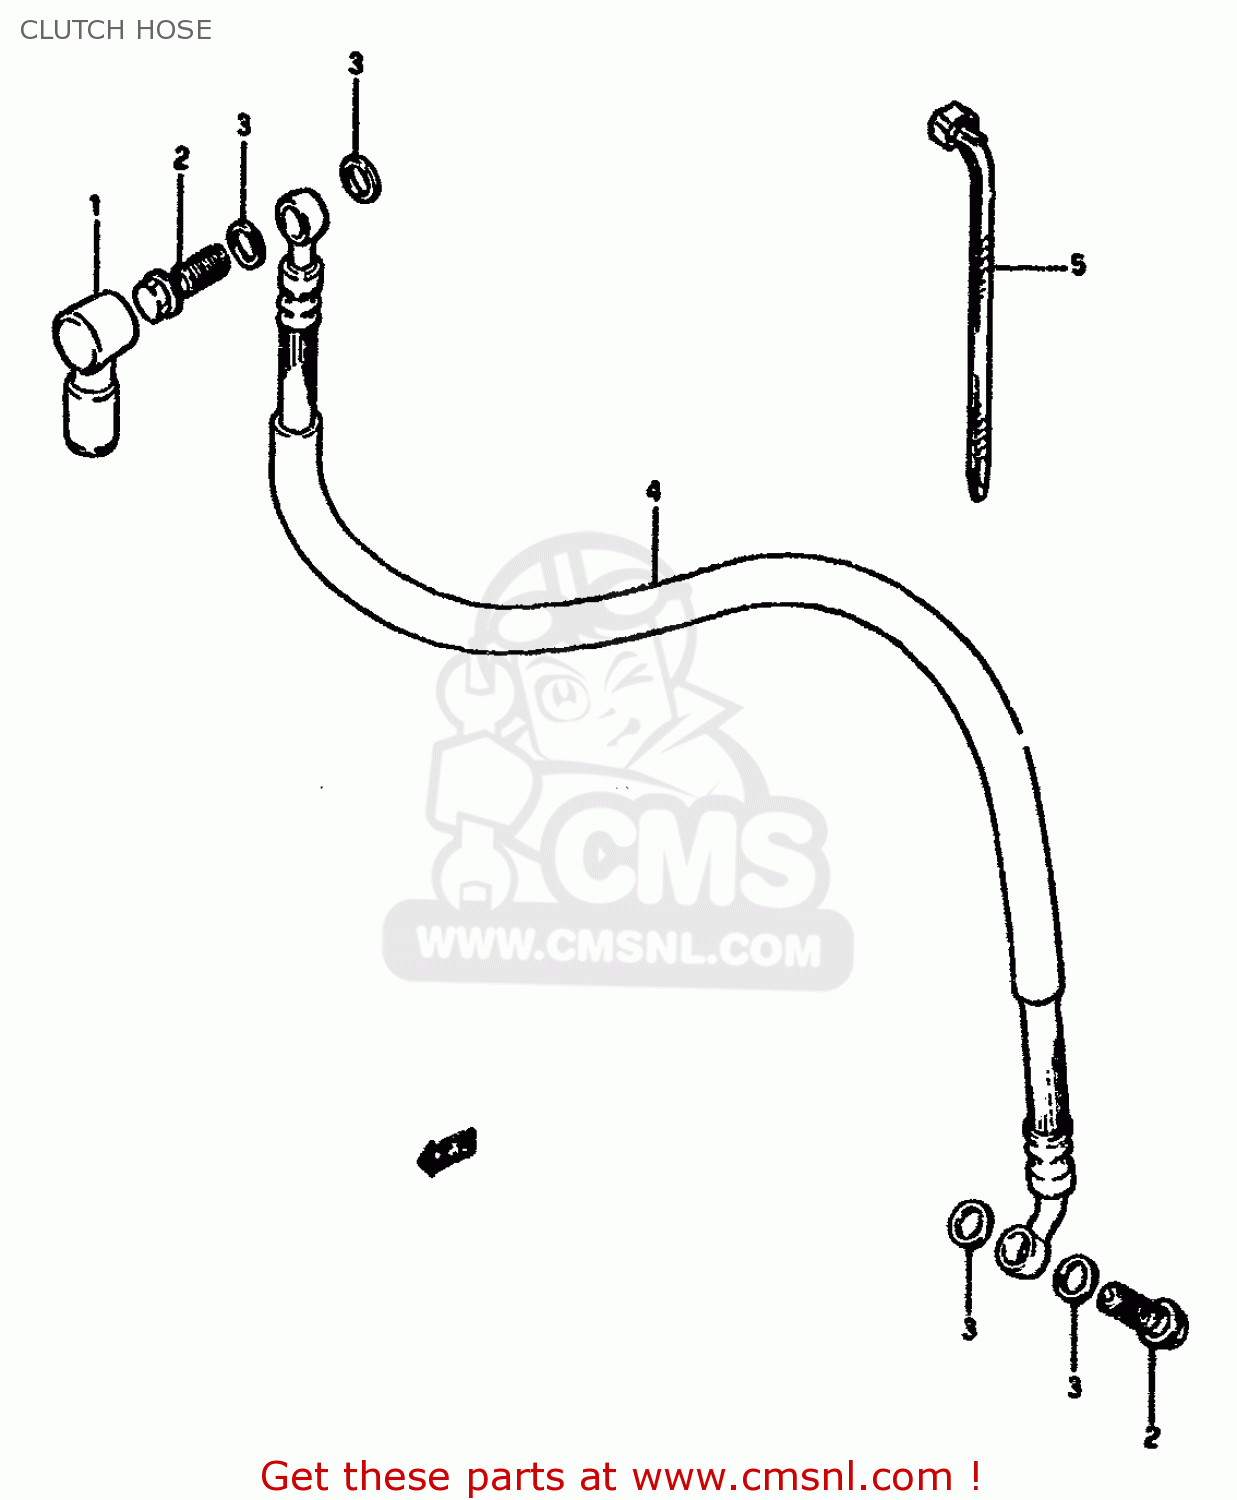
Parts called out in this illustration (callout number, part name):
1	BOOT,MASTER CYLINDER
2	BOLT UNION
3	WASHER(10X15X1.5)
4	HOSE,CLUTCH
5	CLAMP(L:165)
